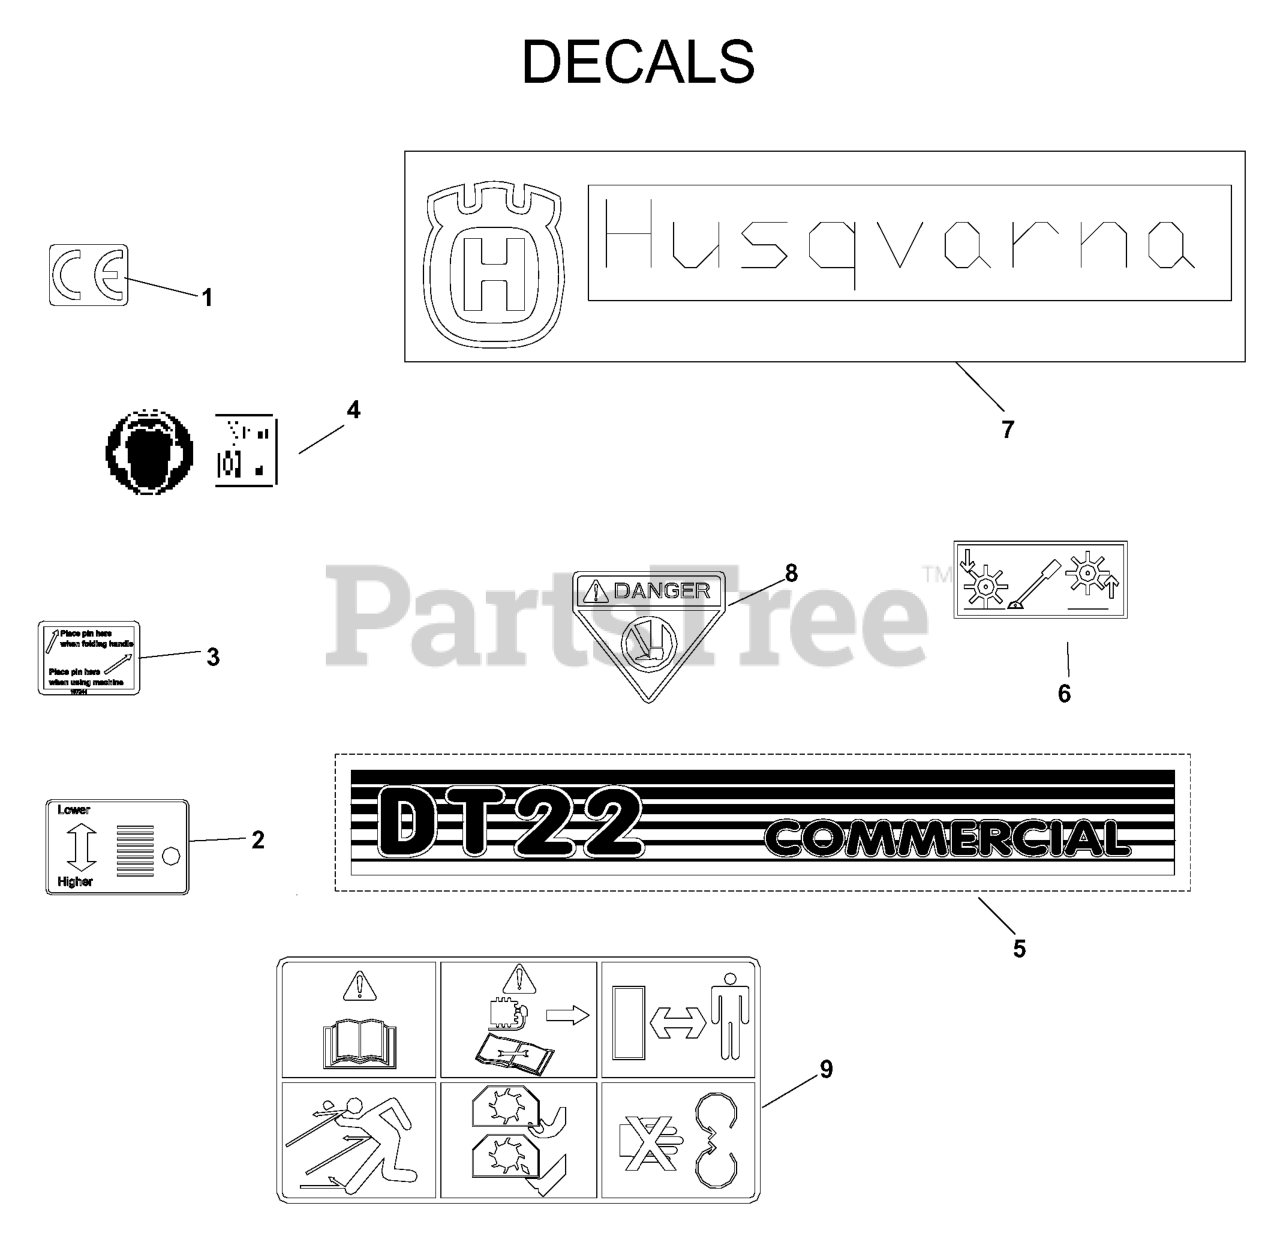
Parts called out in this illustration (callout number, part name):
2	DECAL, PEDAL HEIGHT
3	DECAL, HANDLE PIN
4	DECAL, SOUND POWER
5	DECAL, DT22B
6	DECAL, HEIGHT ADJUST
7	DECAL, HUSQVARNA 12"
9	DECAL, SAFETY GRAPHICS
